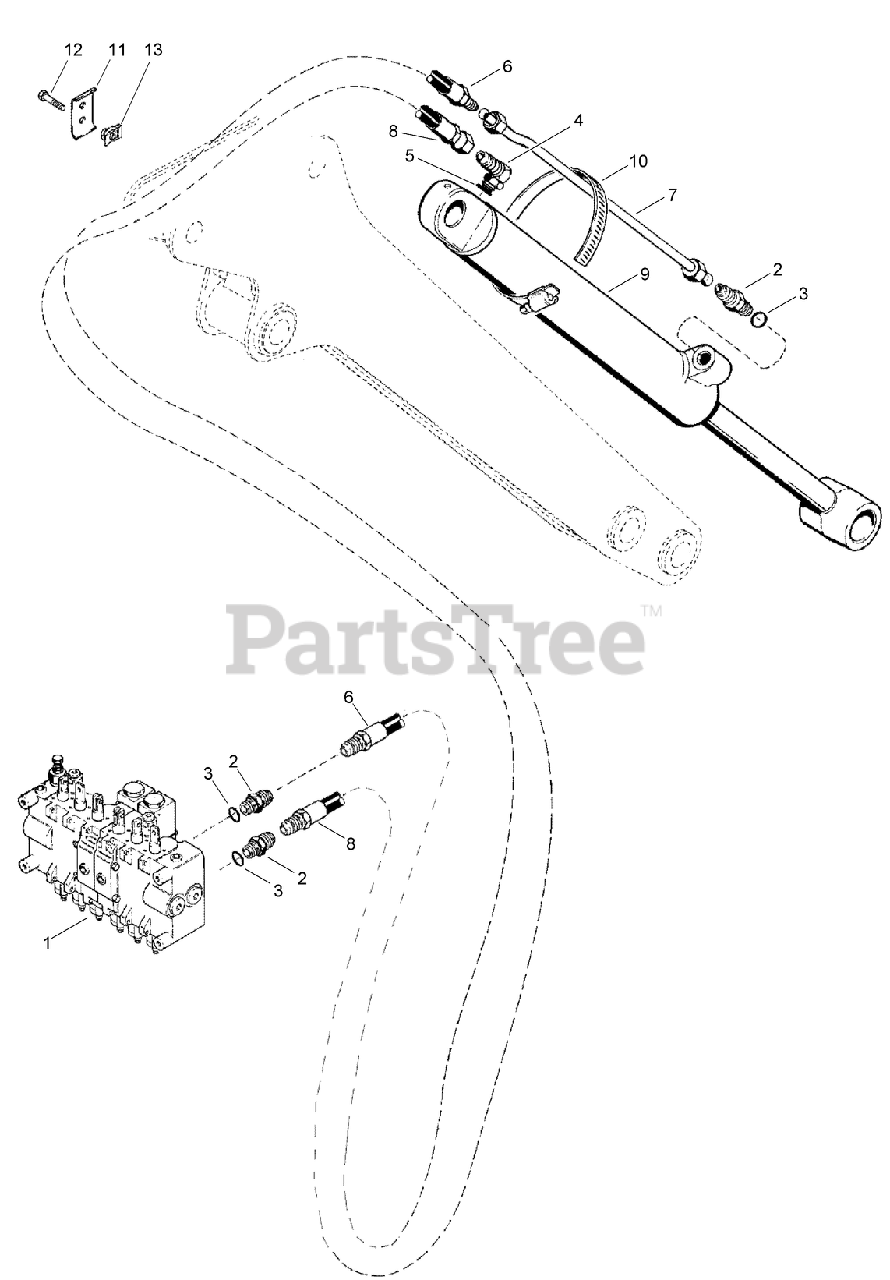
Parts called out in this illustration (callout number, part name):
1	HYD CONTROL VALVE ASM
2	CONNECTOR-Str Thd 1/2, 37FL-ORB 1/2
3	O-RING
4	ELBOW-90 DEG
5	O-RING
6	HOSE-3330 mm (131-1/8 inch) long, to closed end of bucket cylinder
7	TUBE-Hydraulic, Bucket
8	HOSE-3310 mm (130-5/16 inch) long, to tube at rod end of bucket cylinder
9	HYD CYLINDER ASM (BUCKET)
10	CLAMP-Hose Type F #60
11	CLAMP-TUBE
12	BOLT-Hex, 5/16 NC x 1-1/2 inch
13	NUT-Prev Trq 5/16 GRA CAD NONDIR
